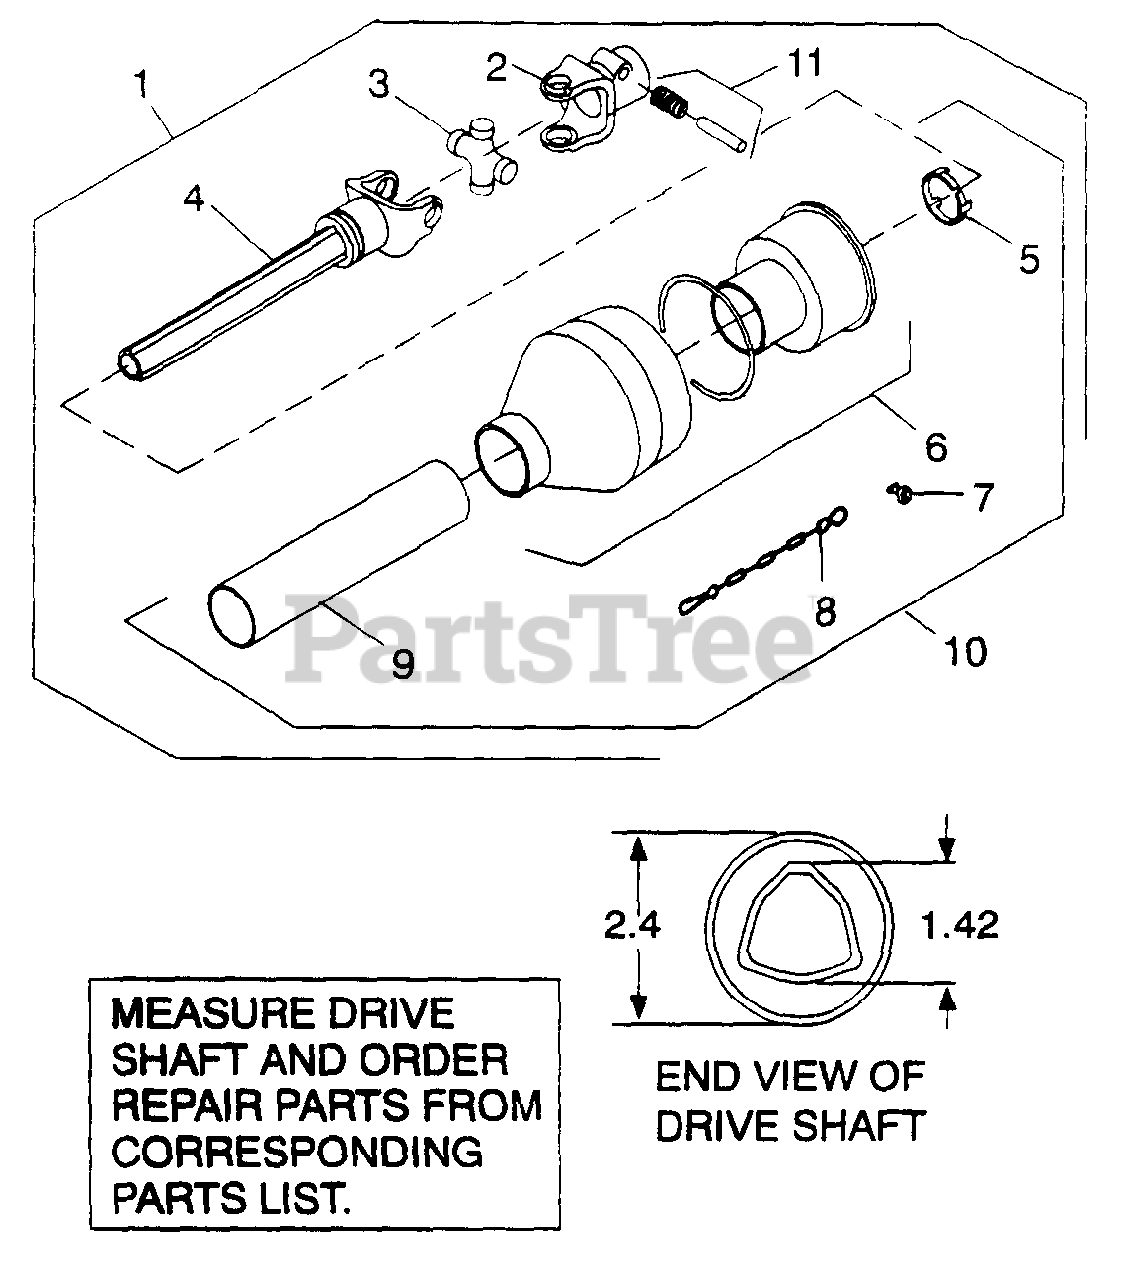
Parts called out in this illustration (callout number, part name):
1	Drive, Profile shield 40, 26.2, 1.38 SP
2	Yoke 40, 1.38 QD
3	U-Joint repair kit 40
4	Yoke and tube, Profile 40 x 26.2
5	Shield bearing kit 40
7	Shield retainer 40
8	Shield tether chain
10	Inner shield assembly, complete, non-rotating 2.40 x 2.23 x 2.69
11	1-3/8 Push pin set
